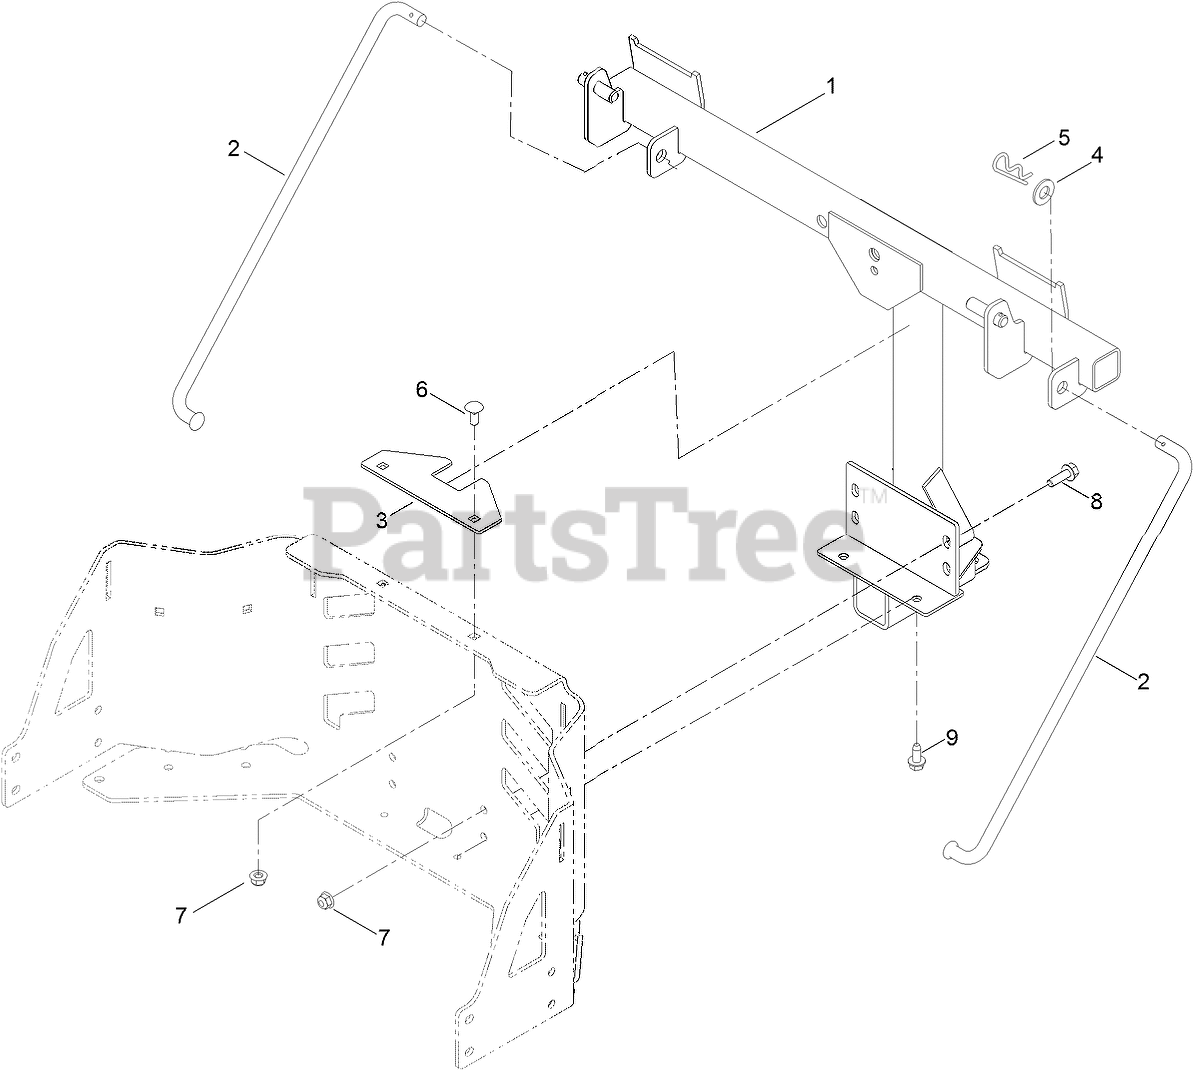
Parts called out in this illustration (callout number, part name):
1	FRAME-PIVOT
2	ROD-SUPPORT
3	BRACKET-STABILIZER
4	WASHER-FLAT
5	PIN-HAIR
6	BOLT-CARR
7	NUT-HF, NI
8	SCREW-HHF
9	SCREW-HWHTF
